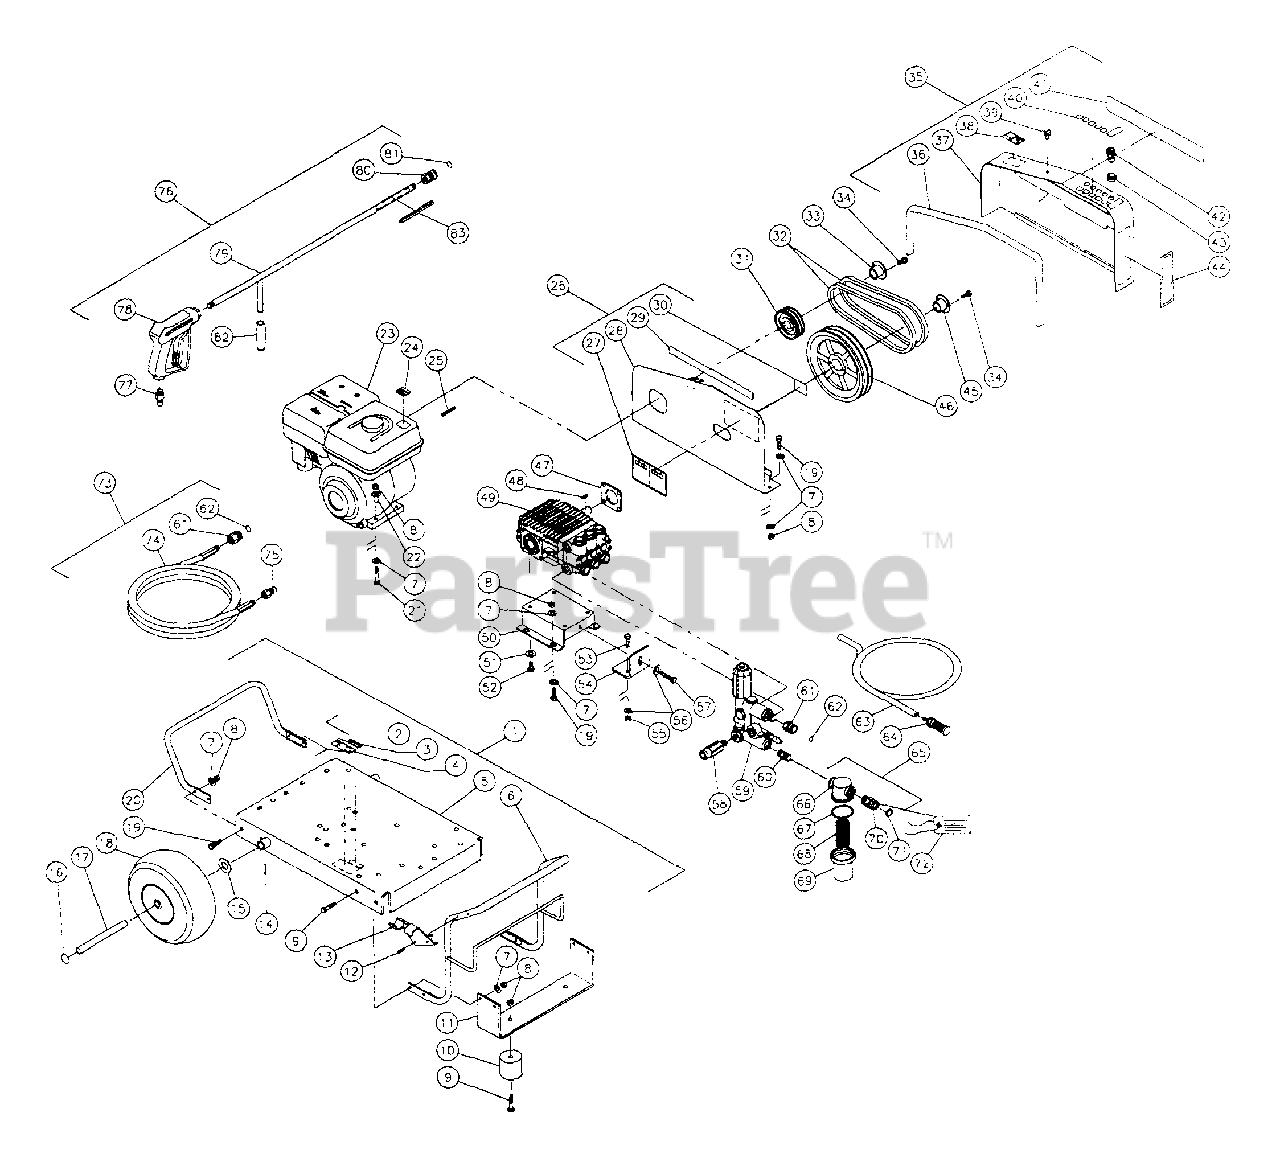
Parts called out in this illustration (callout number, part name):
1	Base Plate Assembly
2	Decal - Clear Laminate
3	Decal - Cold Water Serial Number
4	Decal - Silver Sticker
5	Base Plate
6	Handle - Front
10	Isolator
11	Underbracket
13	Wand holder - Plastic
14	Roll Pin
20	Handle - Rear
22	Engine Shim
23	Engine - 9 HP
24	Decal - Caution Allow to Cool
26	Beltguard Back Assembly
27	Decal - Caution/Warning Statements
28	Beltguard Back-Small
29	Edging (1" x 13.5")
30	Decal - Warning Beltguard in Place
31	Sheave 2AG32D
32	Belt - Engine A X 33
34	Bolt - with bushing
35	Beltguard Cover Assy
36	Edging (1" x 34.5")
37	Beltguard Cover - Small
38	Decal-Warning Muffler Hot
39	Fastener
40	Decal - Nozzles 0ø, 15ø, 25ø, 40ø
41	Decal -
42	Nozzle - 00045
42	Nozzle - 40045
44	Operating Instructions
46	Sheave 2AK74H
47	Isolator - Pump
48	Key - with pump
50	Pump Bracket
51	Washer - with pump
52	Bolt - with pump
54	Brace Tightener
58	Heat Dump Valve
59	Unloader
60	Hex Nipple
61	Quick Connect Socket
63	Detergent Hose (4')
64	Detergent Strainer
65	Strainer Complete
66	Strainer Cap
67	Strainer Gasket
68	Strainer Steel Screen
69	Strainer Bowl
70	Garden Hose Swivel
71	Garden Hose Gasket
72	Tag - Water Supply Inlet
73	Pressure Hose Assy
74	Pressure Hose 3/8" x 50' 3000 PSI
75	Quick Connect Plug - Female 3/8"
76	Gun/Wand Assy
77	Quick Connect Plug - Male 3/8"
79	Wand with 36" Handle
80	Quick connect socket 1/4"
82	Handle Grip for Wand
83	Decal - Warning Risk of injection
